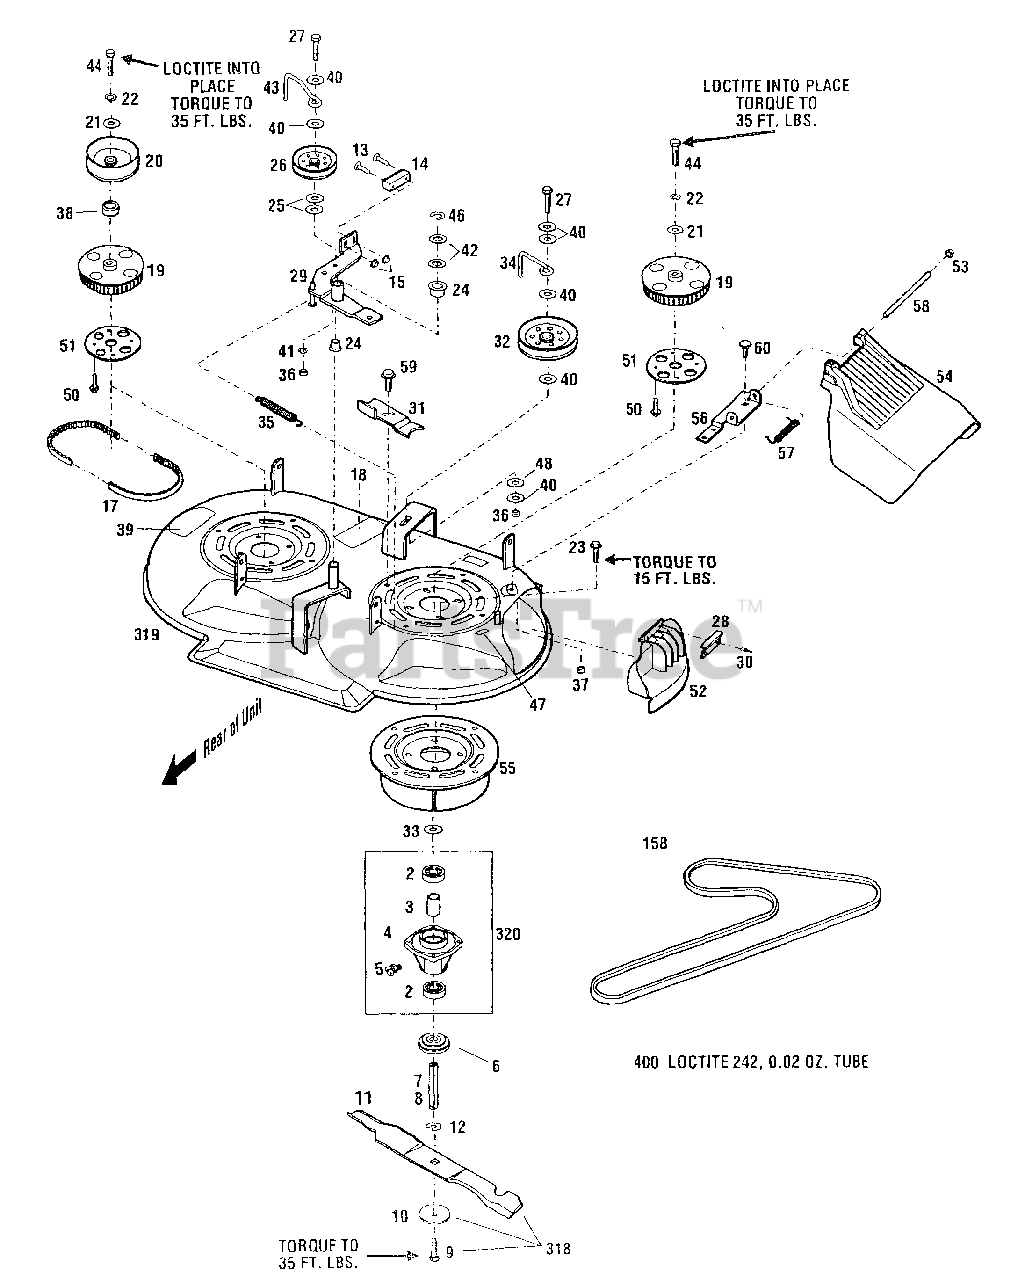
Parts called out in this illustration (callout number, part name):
2	Ball Bearing
3	Spacer
4	Mower Spindle
5	Grease Fitting
6	Blade Spacer
7	Right Spindle Shaft
8	Left Spindle Shaft (long)
9	Screw, 7/16-14 x 1
10	Belleville Washer
11	Blade, 33" Mulching
12	Retaining Ring
13	Flat Head Screw, #10-24 x 1-1/4
14	Brake Pad
15	Nylon Locknut #10-24
17	Toothed Drive Belt
18	Caution Decal
19	Cogged Pulley, 56T
20	Drive Pulley
21	Flat Washer 7/16
22	Lock Washer, 7/16
23	Flange Lock Screw, 5/16-18 x 1
24	Flange Bushing
25	Flat Washer
26	Idler Pulley
27	Hex Head Capscrew, 3/8-16 x 2-1/2
28	Adapter Trim
29	Idler Arm
30	Pop Rivet
31	Belt Tension Adjustment Bracket
32	Idler Pulley
33	Special Thrust Washer
34	Belt Guide
35	Extension Spring
36	Nut, 3/8-16
37	Locknut, 5/16-18
38	Pulley Spacer
39	Danger Decal
40	Flat Washer, 3/8 x 3/4
41	Lock Washer, 3/8
42	Flat Washer
43	Belt Guide
44	Screw, 7/16-14 x 1-1/4
46	Retaining Ring
47	Warning Decal
48	Pyramid Washer, 3/8
50	Triplask Screw, 1/4-20 x 5/8
51	Sprocket Plate
52	Mulcher Cover, Fold-Up Style
54	Discharge Chute
55	Weldment Doubler
56	Bracket, Chute Hinge
57	Spring, Discharge Chute
58	Pin, Discharge Chute
59	Screw, Thread-Forming
60	Bolt, Carriage, 3/8-18 x 3/4
158	V-Belt
318	Mulching Blade Kit
319	Mower Deck Assembly
320	Mower Spindle Assembly
400	Loctite 242, 0.02 oz. Tube
